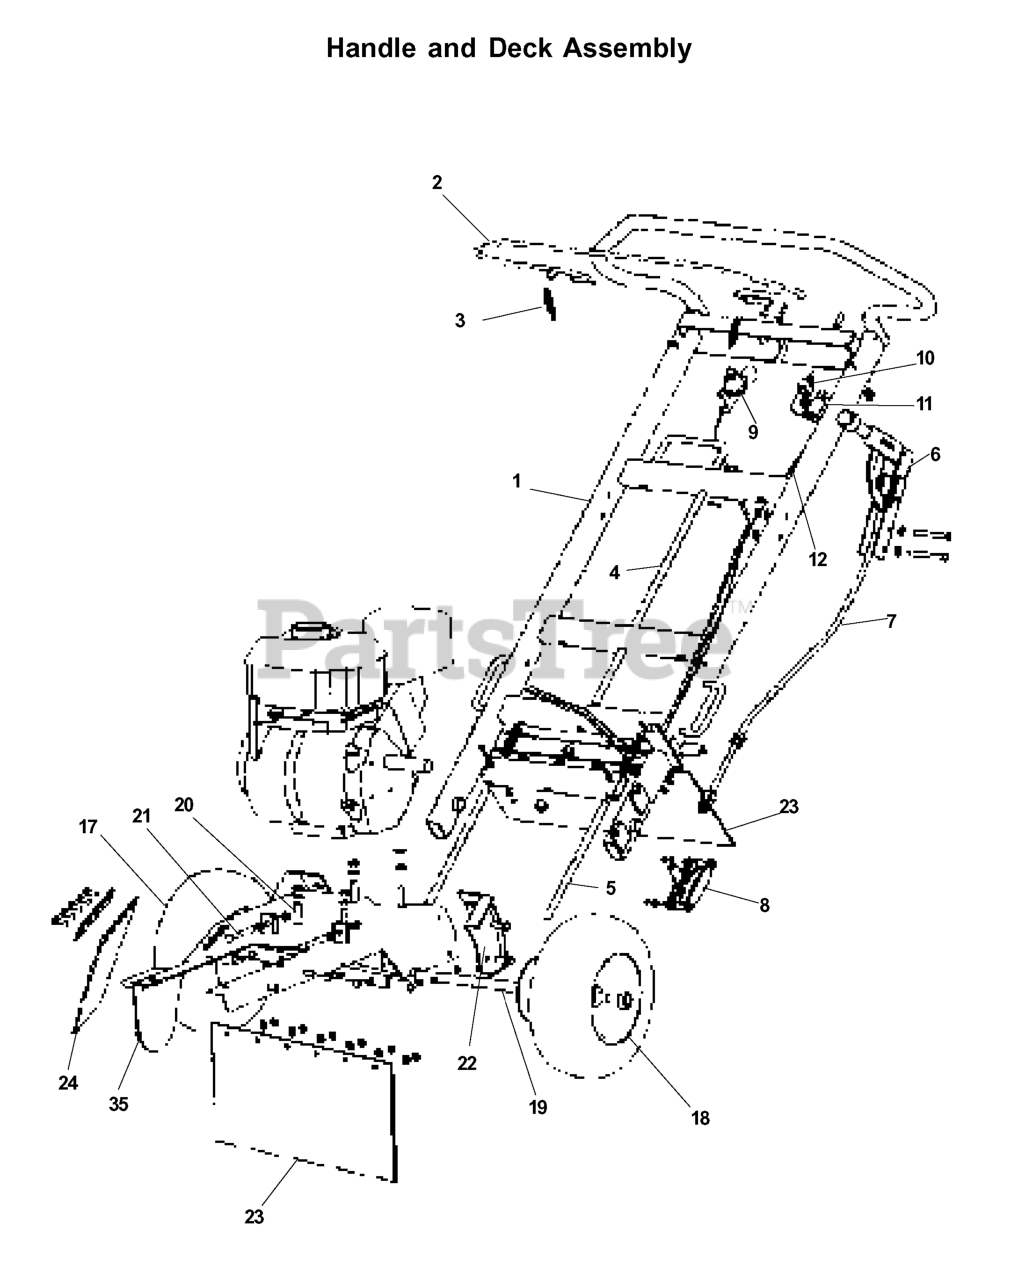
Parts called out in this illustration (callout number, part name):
1	HANDLE
2	BAIL ASSY
3	EXTENSION SPRING
4	HANDLE ADJ LEVER ASSY
5	HANDLE ADJUSTMENT PIN ASSY
6	BRAKE LEVER KIT
7	BRAKE CABLE
8	BRAKE CALIPER ASSY
9	THROTTLE CABLE ASSY
10	ON/OFF TOGGLE SWITCH
11	PLUNGER SWITCH ASSY
12	WIRE HARNESS ASSY
13	RIGHT WHEEL
14	KIT, LEFT WHEEL
15	AXLE
16	ENGINE BOLT KIT
17	JACK SCREW
18	HANDLE ADJUSTMENT BRACKET
19	REAR DEFLECTOR KIT
20	RIGHT SIDE DEFLECTOR
21	DECK
